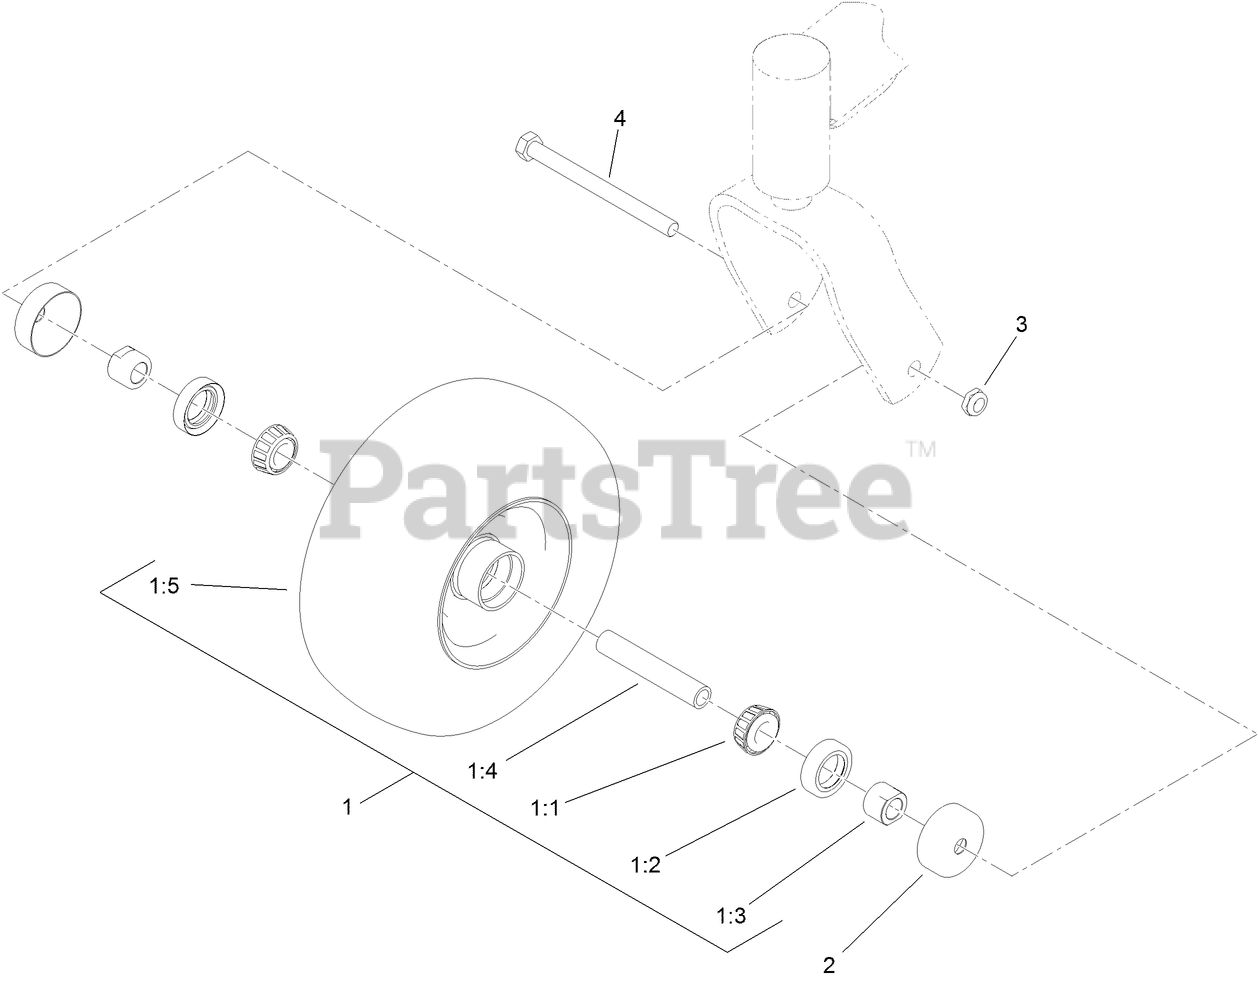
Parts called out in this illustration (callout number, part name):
1	WHEEL AND BEARING ASM
1:1	BEARING-CONE, TAPER
1:2	SEAL-CASTER
1:3	SPACER-NUT
1:4	AXLE-CASTER
1:5	WHEEL AND TIRE ASM
2	GUARD-SEAL
3	NUT-LOCK, NI
4	SCREW-HH
